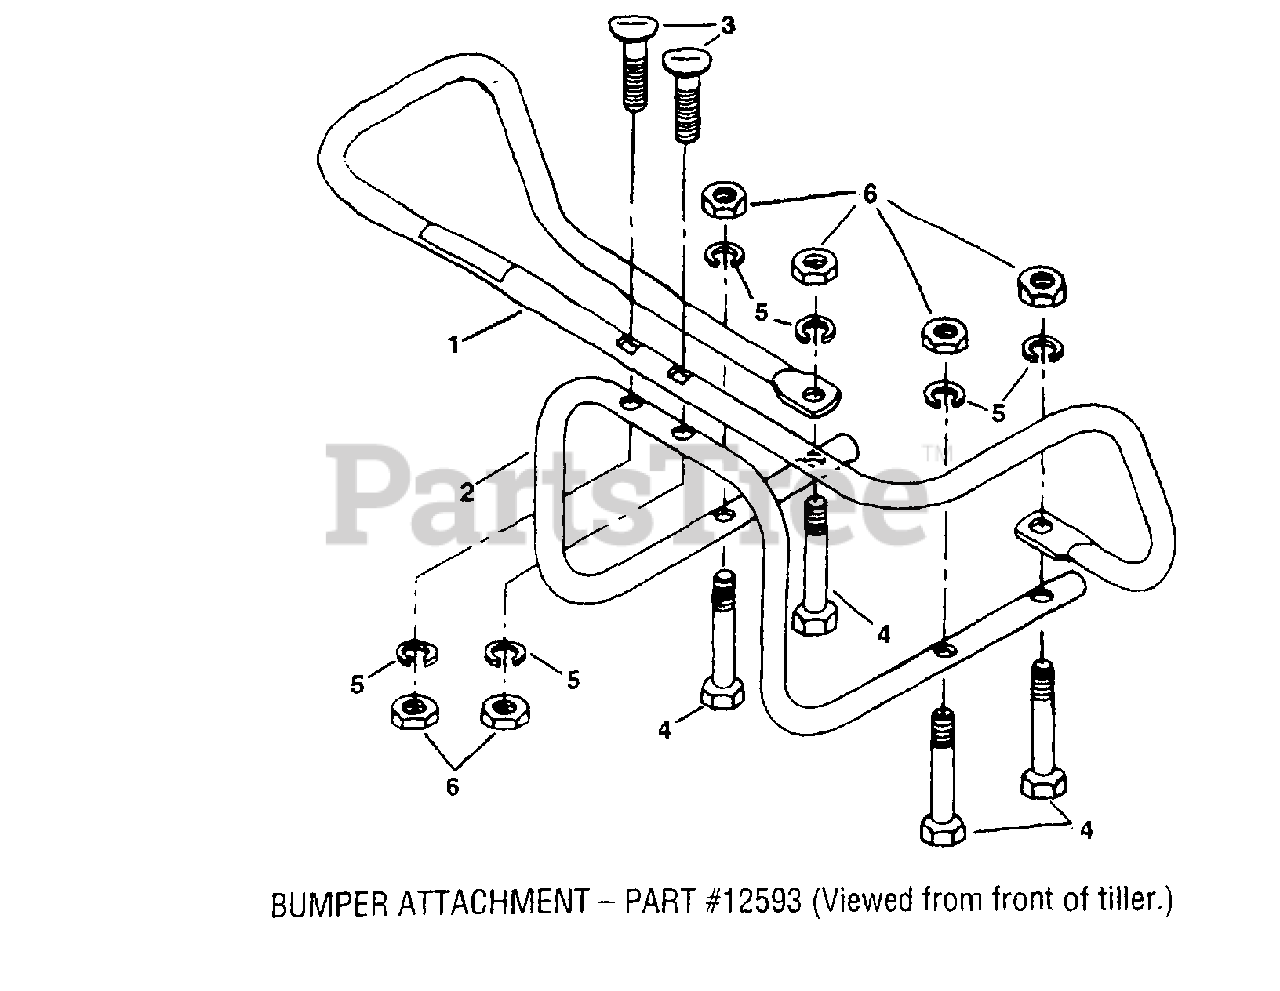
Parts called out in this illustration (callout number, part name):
1	Bumper, Top Section 1
2	Bumper, Bottom Section 1
3	Curved Hd. Screw, 5/16-18 x 2
4	Hex Hd. Screw, 5/16-18 x 2-1/2,
5	Lockwasher, 5/16,
6	Hex Nut, 5/16-18
